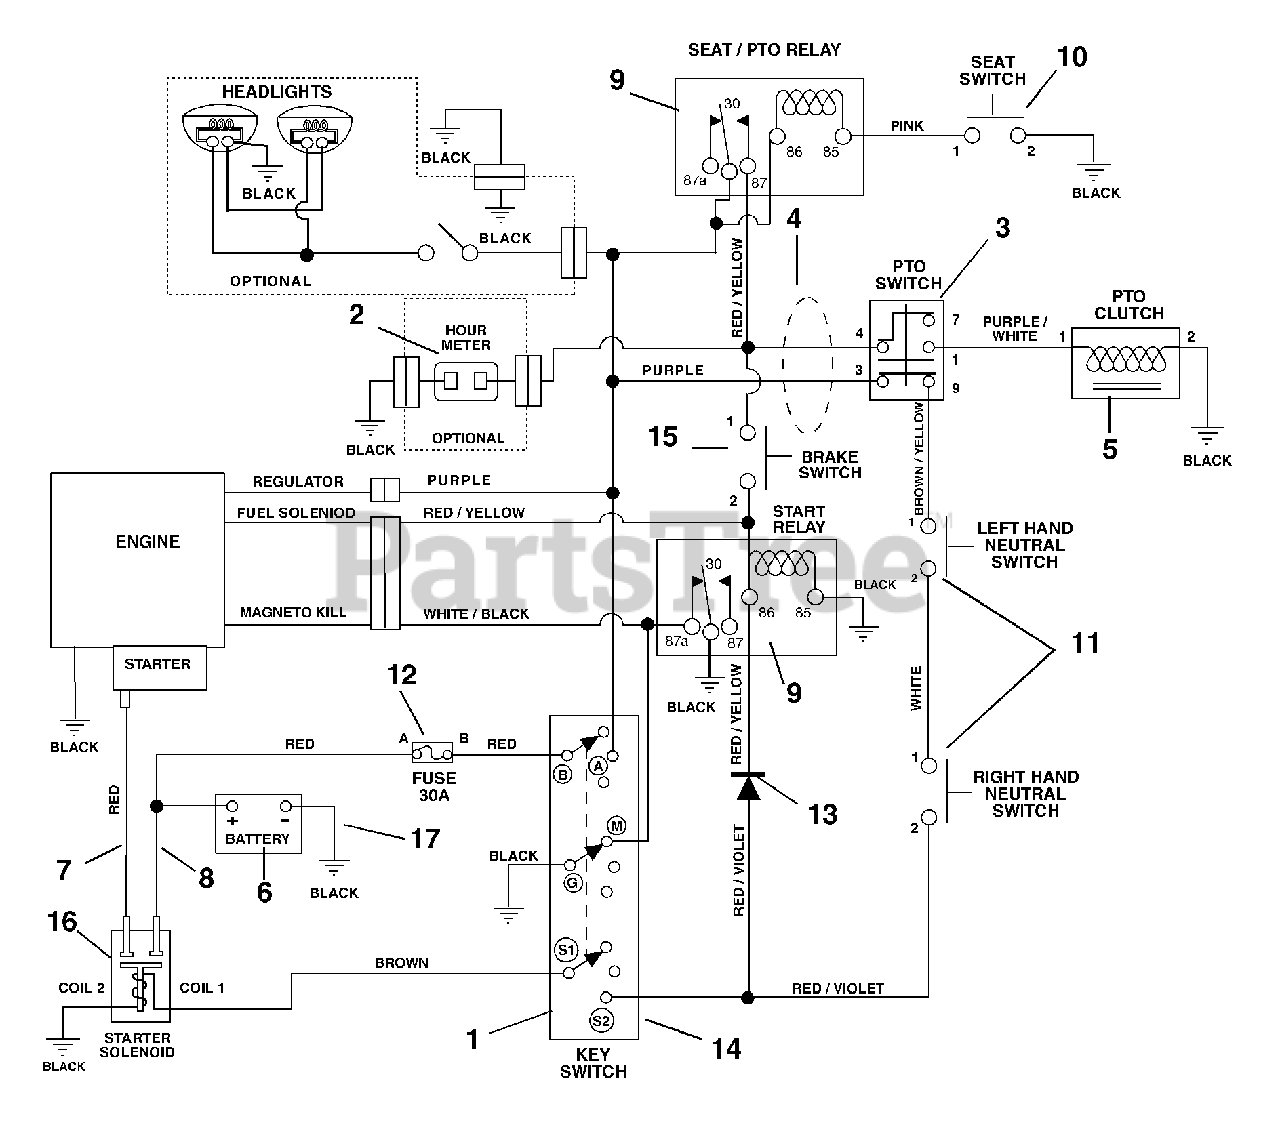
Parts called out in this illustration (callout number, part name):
1	Key Switch
2	Hour Meter
3	Switch-Clutch
4	Harness-Wiring
5	Clutch / Brake-Electric
6	Battery with Tube
7	Start Cable
8	Starter Cable
9	Relay
10	Switch-Seat
11	Switch-Neutral
12	30 AMP Fuse
13	Plug-Molded Diode
14	Cap-Ignition Switch
15	Switch-Brake
16	Solenoid
17	Ground Cable
